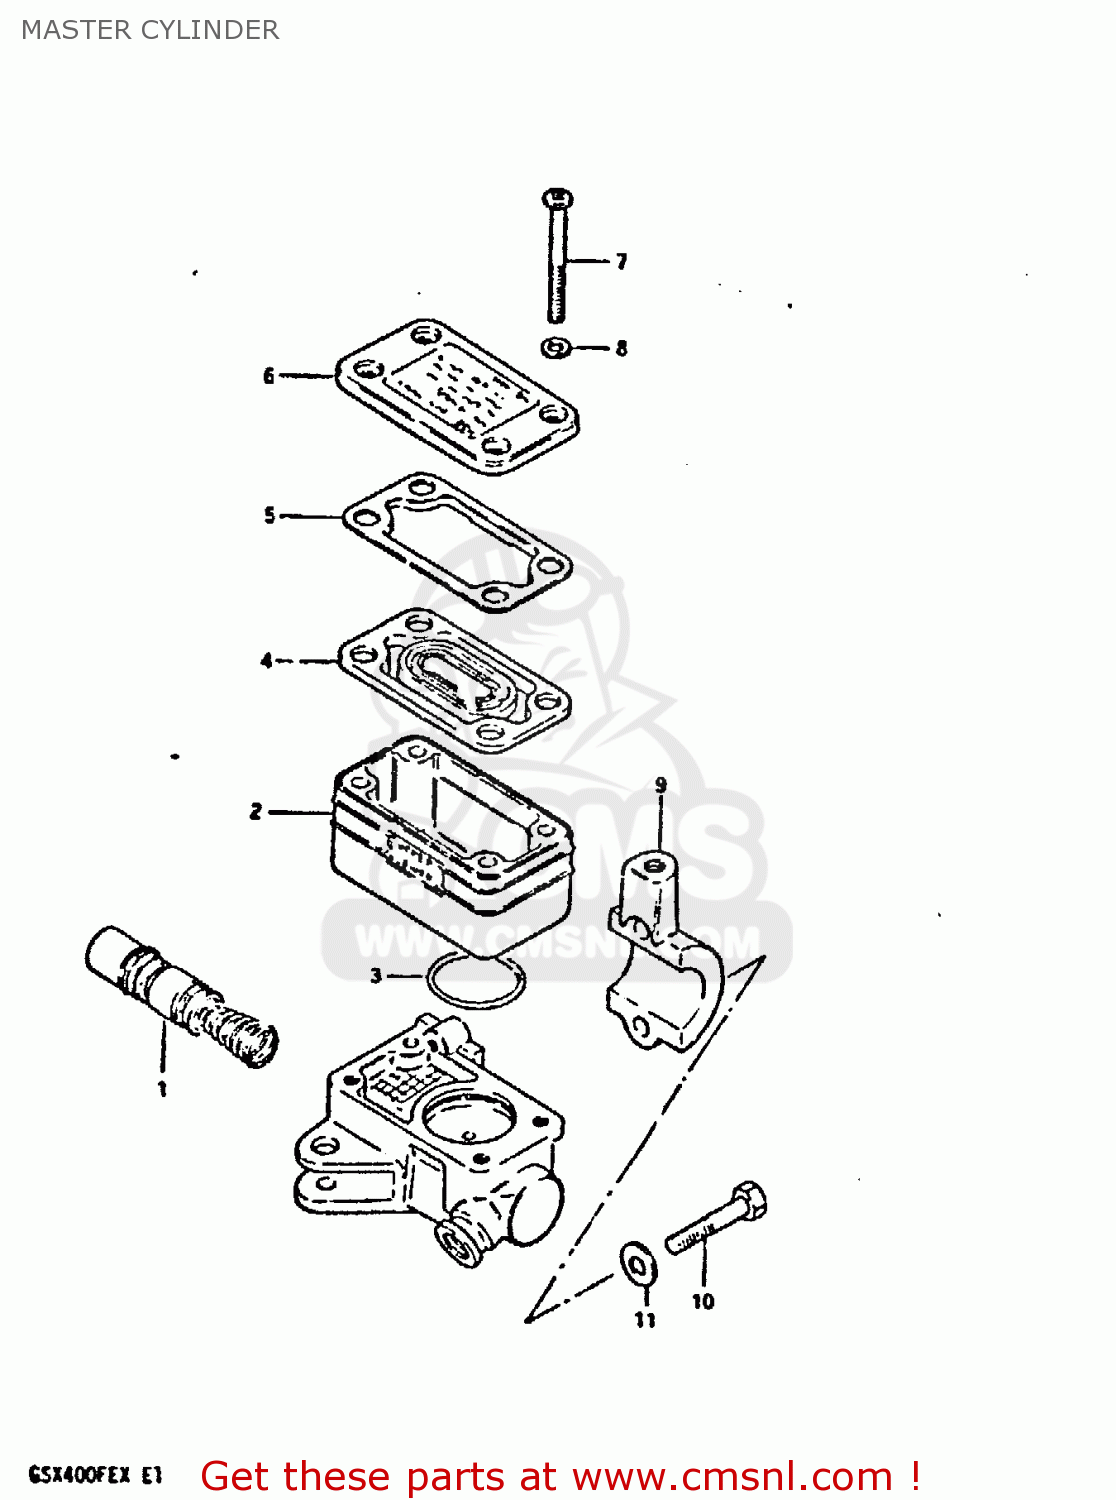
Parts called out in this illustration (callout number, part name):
1	PISTON & CUP SET
2	RESERVOIR
3	O RING
4	DIAPHRAGM
5	PLATE,DIAPHRAGM
6	CAP
7	SCREW
8	WASHER
9	HOLDER
10	BOLT
11	WASHER
